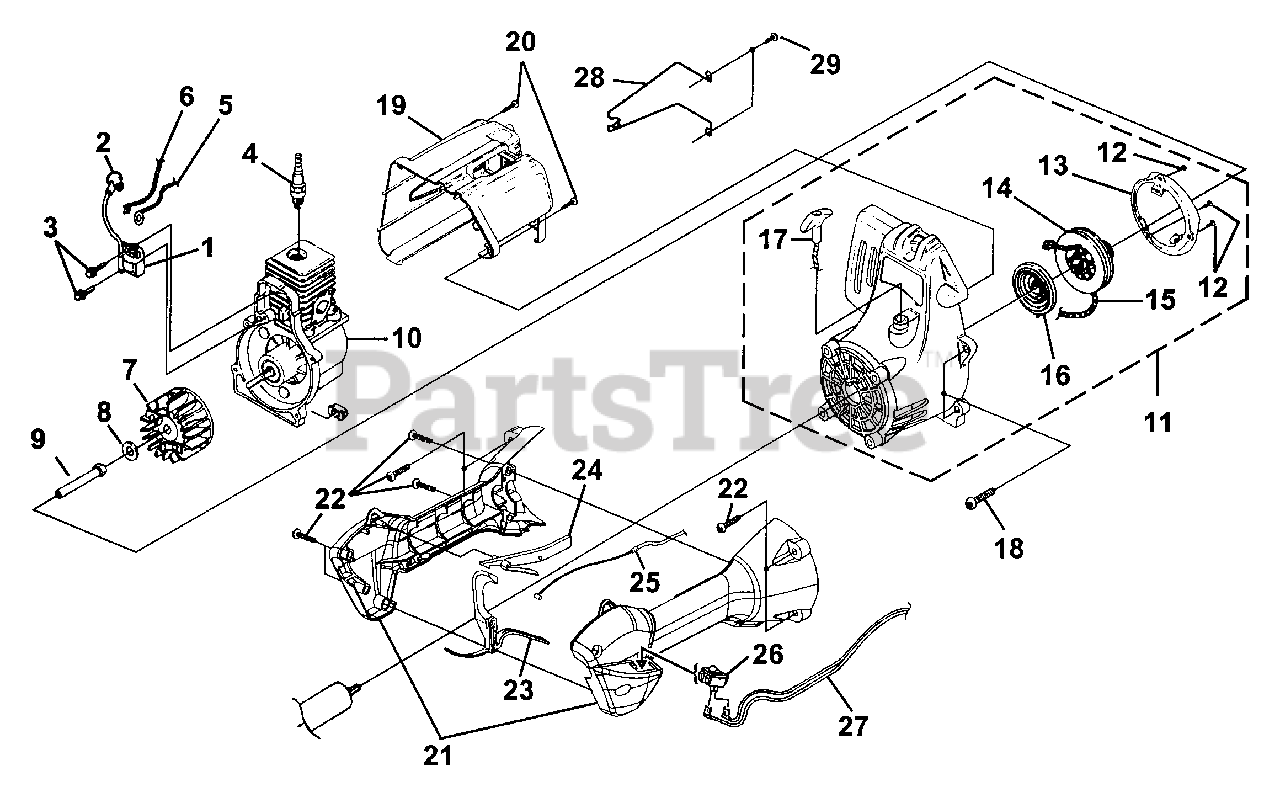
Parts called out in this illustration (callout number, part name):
1	MODULE-Ignition
2	TERMINAL & COVER
3	SCREW-Taptite (8-32 X 1")
4	SPARK PLUG - Resistor
5	LEAD-Ground
6	LEAD-Electrical
7	ROTOR KIT
8	WASHER-Flat
9	CONNECTOR-Drive
10	SHORT BLOCK
11	COMPLETE STARTER ASSEMBLY
12	SCREW-Taptite (8-16 X 1/2")
13	BAFFLE-Air
14	PULLEY-Starter
15	ROPE-Starter (42")
16	SPRING & CONTAINER
17	GRIP-Starter
18	SCREW-Taptite (10-24 X 3/4")
19	HOUSING-Rear Kit
20	SCREW-Taptite (10-14 X 7/8")
21	CONTROL HANDLE ASSY.
22	SCREW-Taptite (10-14 X 7/8")
23	TRIGGER-Throttle
24	INTERLOCK-Throttle
25	CABLE-Throttle
26	SWITCH
27	LEAD-Electrical
28	GUARD-Muffler
29	SCREW-Thread Forming (10-14 X 1/2")
